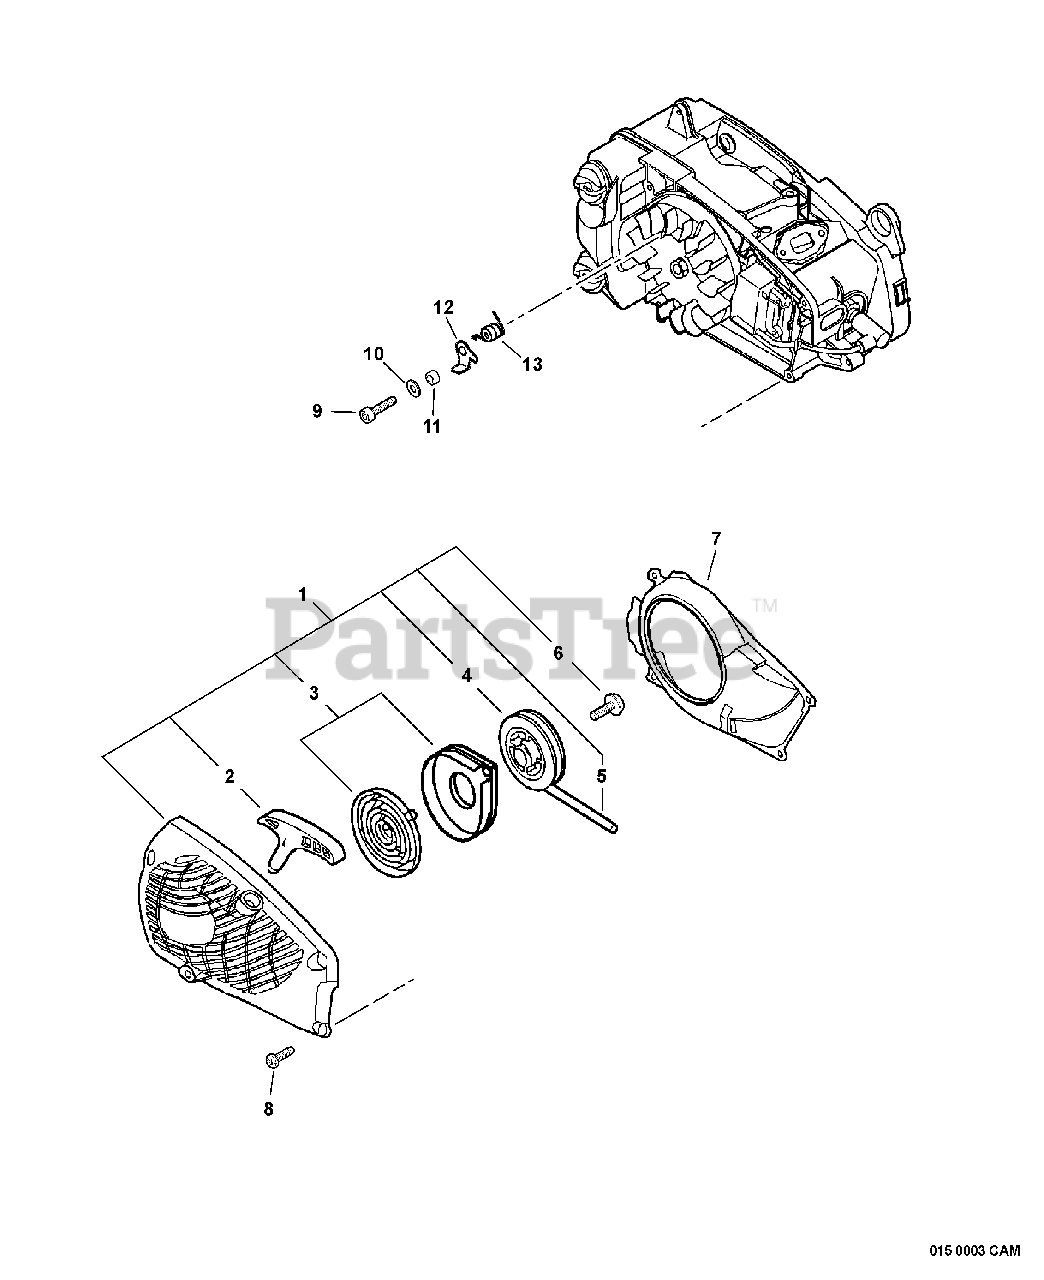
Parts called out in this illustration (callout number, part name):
1	STARTER ASSY
2	GRIP, STARTER
3	REWIND SPRING ASSY
4	REEL, ROPE
5	ROPE, STARTER - 3X920
7	COVER, FAN
9	SCREW - 5X14
10	WASHER - 5
12	PAWL, STARTER
13	SPRING, RETURN
